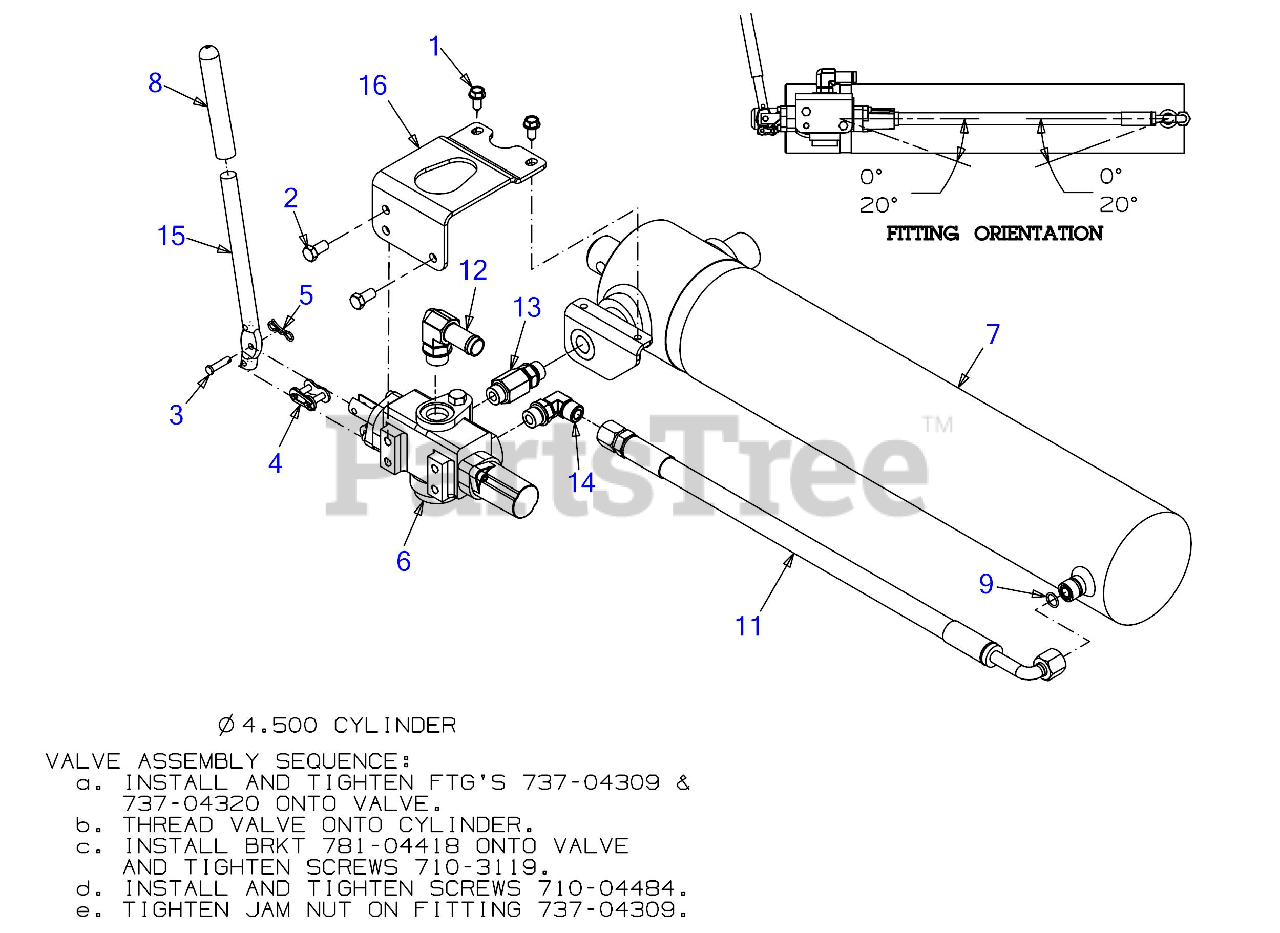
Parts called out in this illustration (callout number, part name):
1	SCREW 5/16-18 x .750
2	SCREW 3/8-16 x .75 GR 5
3	CLEVIS PIN .25 x 1.00
4	VALVE HANDLE LINK
5	BOW TIE COTTER PIN 1/4-5/16
6	LOGSPLITTER VALVE
7	HYDRAULIC CYLINDER
11	HYDRAULIC HOSE
12	HYDRAULIC FITTING
13	HYDRAULIC FITTING
14	HYDRAULIC FITTING
15	CONTROL VALVE HANDLE
16	VALVE BRACKET
